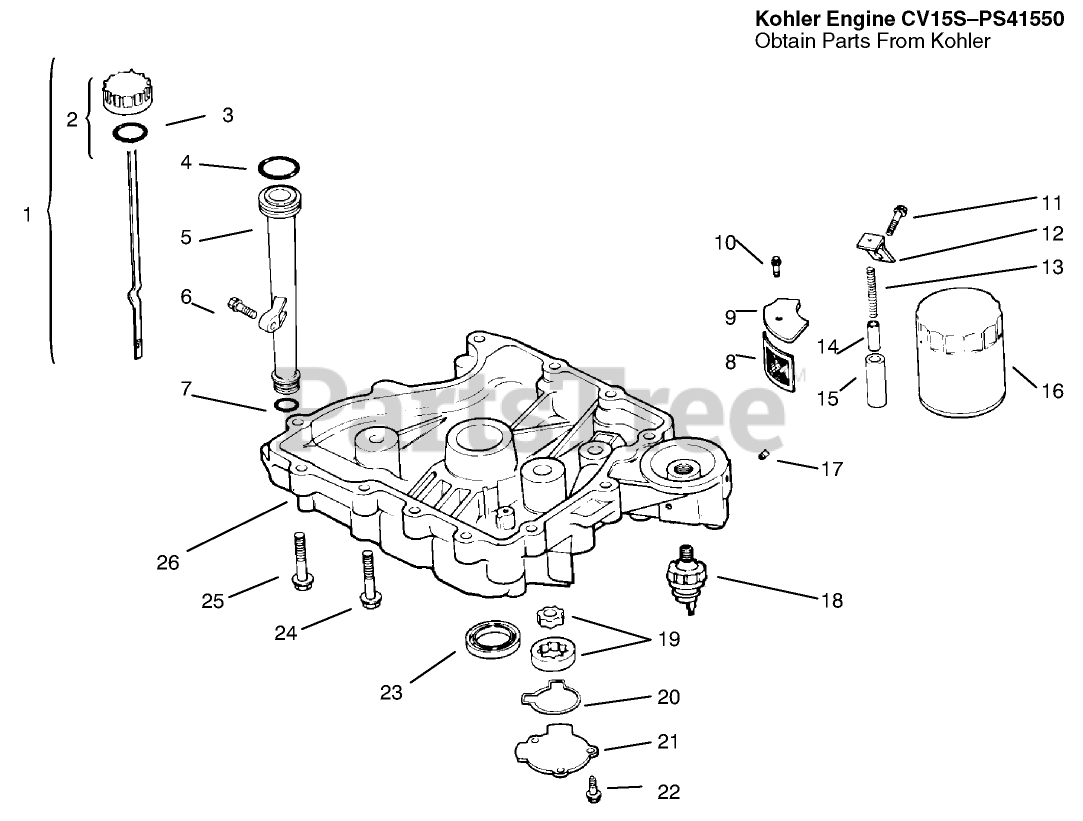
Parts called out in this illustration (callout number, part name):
1	Dipstick INC 2-3 (Only On: 72042, 72063, 72062, 72043)
2	Kit-Oil Fill Cap (Incl. Ref. #7)
3	ORing
4	O Ring-Upper Fill Tube (Only On: 72103)
5	Tube-Oil Fill (Only On: 72103, 72083)
7	O-Ring-Lower Fill Tube (Only On: 72042, 72063, 72062, 72043)
8	Screen-Oil Pickup
9	Cover-Oil Pickup Screen (Only On: 72042, 72063, 72062, 72043)
10	Screw M5x0.8x16 (Only On: 72042, 72063, 72062, 72043)
11	Screw M10x1.5x25 (Only On: 72042, 72063, 72062, 72043)
12	Bracket-Oil Pump Relief (Only On: 72042,72043,72062,72063)
13	Spring-Oil Relief Valve (Only On: 72042,72043,72062,72063)
14	Piston-Oil Relief Valve (Only On: 72042, 72063, 72062, 72043)
15	Body-Oil Relief Valve (Only On: 72042, 72063, 72062, 72043)
16	Filter-Oil
18	Switch-Oil Pressure
19	Pump-Oil (Only On: 72042, 72063, 72062, 72043)
20	O Ring-Oil Pump Cover (Only On: 72042,72043,72062,72063)
21	Cover-Oil Pump (Only On: 72042,72043,72062,72063)
22	Screw M5x0.8x16 (Only On: 72042, 72063, 72062, 72043)
23	Seal-Crankshaft (Only On: 72042, 72043, 72062, 72063)
25	Screw M8x1.25x45 (Only On: 72103, 72083)
26	Pan-Oil (Only On: 72042,72043,72062,72063)
